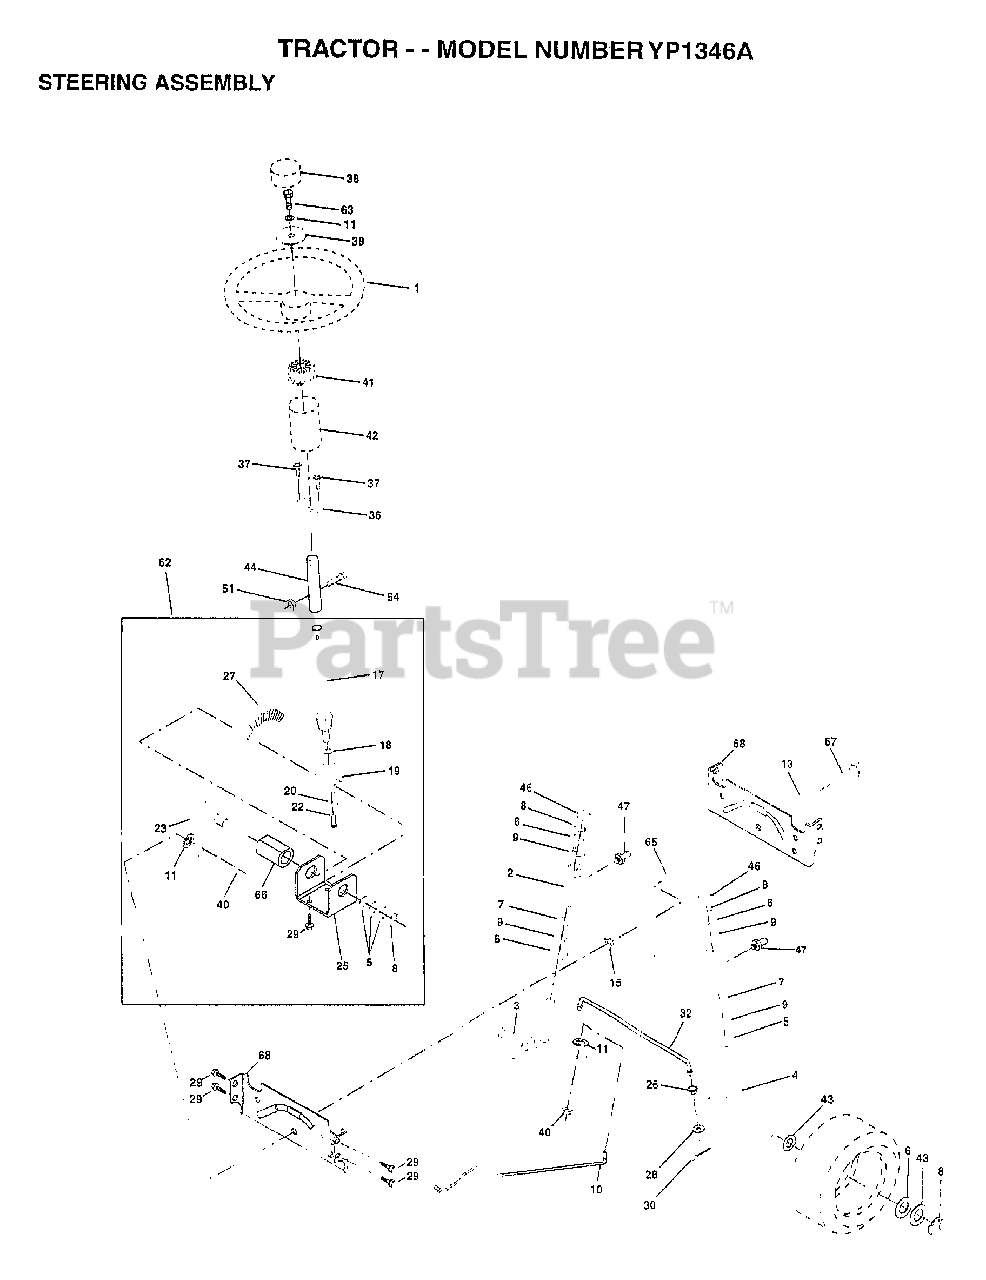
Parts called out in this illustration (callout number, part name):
1	WHEEL STR AYP BLK
2	AXLE ASM
3	SPINDLE.ASM.LH
4	"SPINDLE ASM,RH"
5	WASHER .T
6	WASHER
7	WASHER
8	RING
9	COL. SRTG. BEAR.
10	DRAGLINK-STAMPED
11	LOCKWASHER
13	BEARING AXLE
15	"NUT-LOC,FLANGE LT"
17	SHAFT ASM STEERIN
18	THRUST WASHER
19	SUPPORT.SHAFT
22	SCREW HEX SOC1/4-
25	BRKT-STEERING
26	BUSHING.DRAGLINK
27	GEAR SECTOR
28	WASHER
29	SCREW
30	COTTER PIN
32	TIE ROD
36	BUSHING.STEERING
37	"SCREW-TT,10-32 FL"
38	CAP STEER AYP
39	WASHER T
40	GRIPCO NUT
41	ADAPTER LT
42	BOOT.STEER.PL
43	WASHER
44	EXT SHAFT STEERIN
46	CAP
47	ZERK M
51	NUT
54	BOLT
62	KIT STEERING ASM
63	BOLT
65	SPACER AXLE
66	"BEARING-ARM,PITMA"
67	BOLT
68	BRACE AXLE
